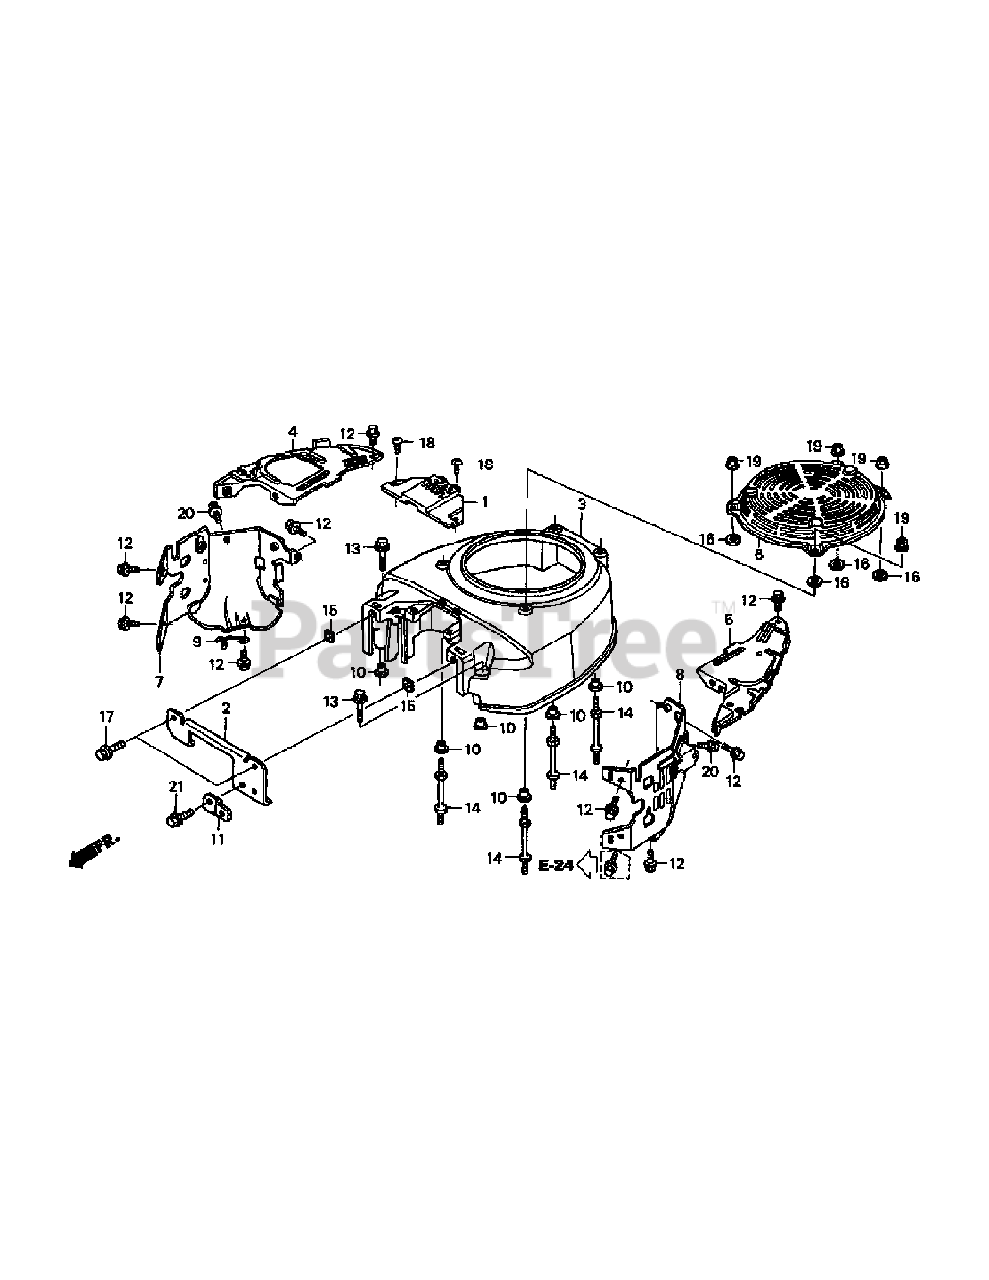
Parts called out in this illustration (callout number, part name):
1	Fuel Pump Cover
2	Fuel Pump Cover
4	Side Plate R.H.
5	Side Plate L.H.
6	Fan Cover Protector
7	Shroud R.H.
8	Shroud L.H.
9	Ignition Tube Clamp
12	Flange Bolt (6x12)
13	Flange Bolt (6x23)
14	Stud Bolt (6x71)
15	Square Nut (5mm)
16	Crank Arm Washer
17	Screw Washer (5x12)
18	Tapping Screw (5x20)
19	Flange Nut (6mm)
20	Flange Bolt (6x8)
21	Flange Bolt (6x12)
